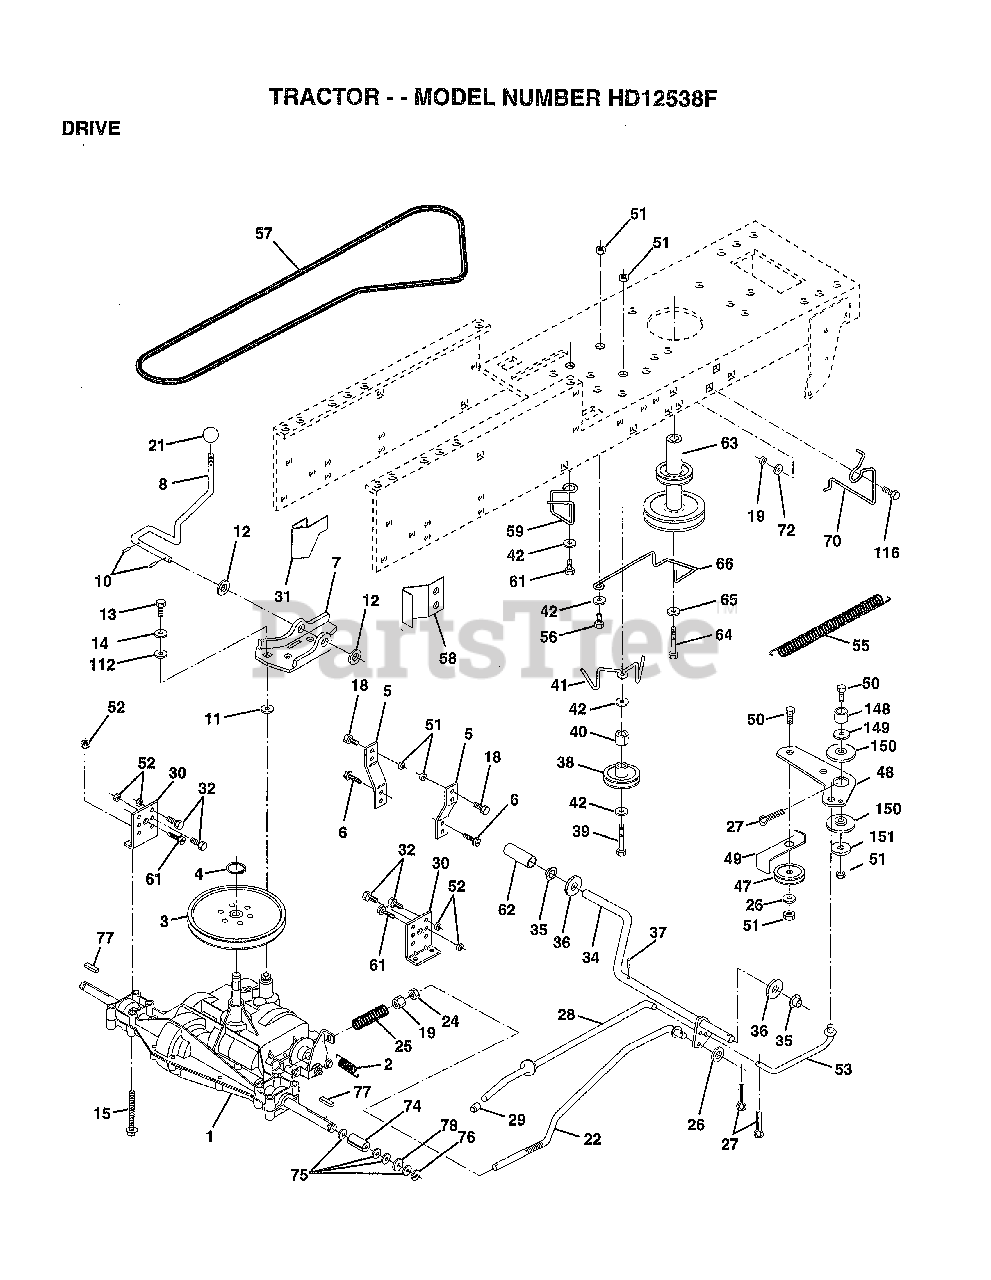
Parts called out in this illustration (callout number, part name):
2	SPRING.BRAKE.RETU
3	PULLEY TRANS
5	STRAP TORQUE
6	SCREW
7	BRKT.SADDLE.SHIFT
8	SHIFT ROD
10	PIN COTTER 1/8
11	WASH-SHFT PLT LT
12	WASHER
13	BOLT.1/4-28.W/PAT
14	LOCKWASHER
15	BOLT.HX.FLG.5/16
18	BOLT
19	NUT
21	KNOB T (1/2-HOLE)
22	BRAKE ROD
24	NUT
25	SPRING ROD LT
26	WASHER
27	COTTER PIN
28	ROD.BRAKE.PARK.LT
29	PLUNGER CAP T
30	TRANSAXLE MTG BKT
31	"KEEPER,BELT LH T"
32	BOLT
34	SHAFT ASM-PEDAL F
35	NYLON BEARING
36	WASHER LT
38	PULLEY.IDLER.FLAT
39	BOLT
40	SPACER T
42	WASHER
48	BELLCRANK.CLUTCH
49	RETAIN BELT
53	"LINK, CLUTCH T"
55	"SPRING, RETURN LT"
57	"V-BELT,95.3"
58	"KEEPER,BELT RH T"
59	KEEPER BELT CNTSP
61	SCREW
62	PEDAL COVER T
63	PULLEY.ENGINE
64	BOLT
65	LOCKWASHER
66	KEEPER-BELT
70	KEEPER BELT ENG
72	WASHER
74	SPACER LT
76	E-RING LT
77	SQUARE KEY
78	WASHER
112	WASHER LT
116	BOLT RDHD 3/8-16
149	SPACER RETAINER
150	BUSHING.NYLON
151	WASHER
